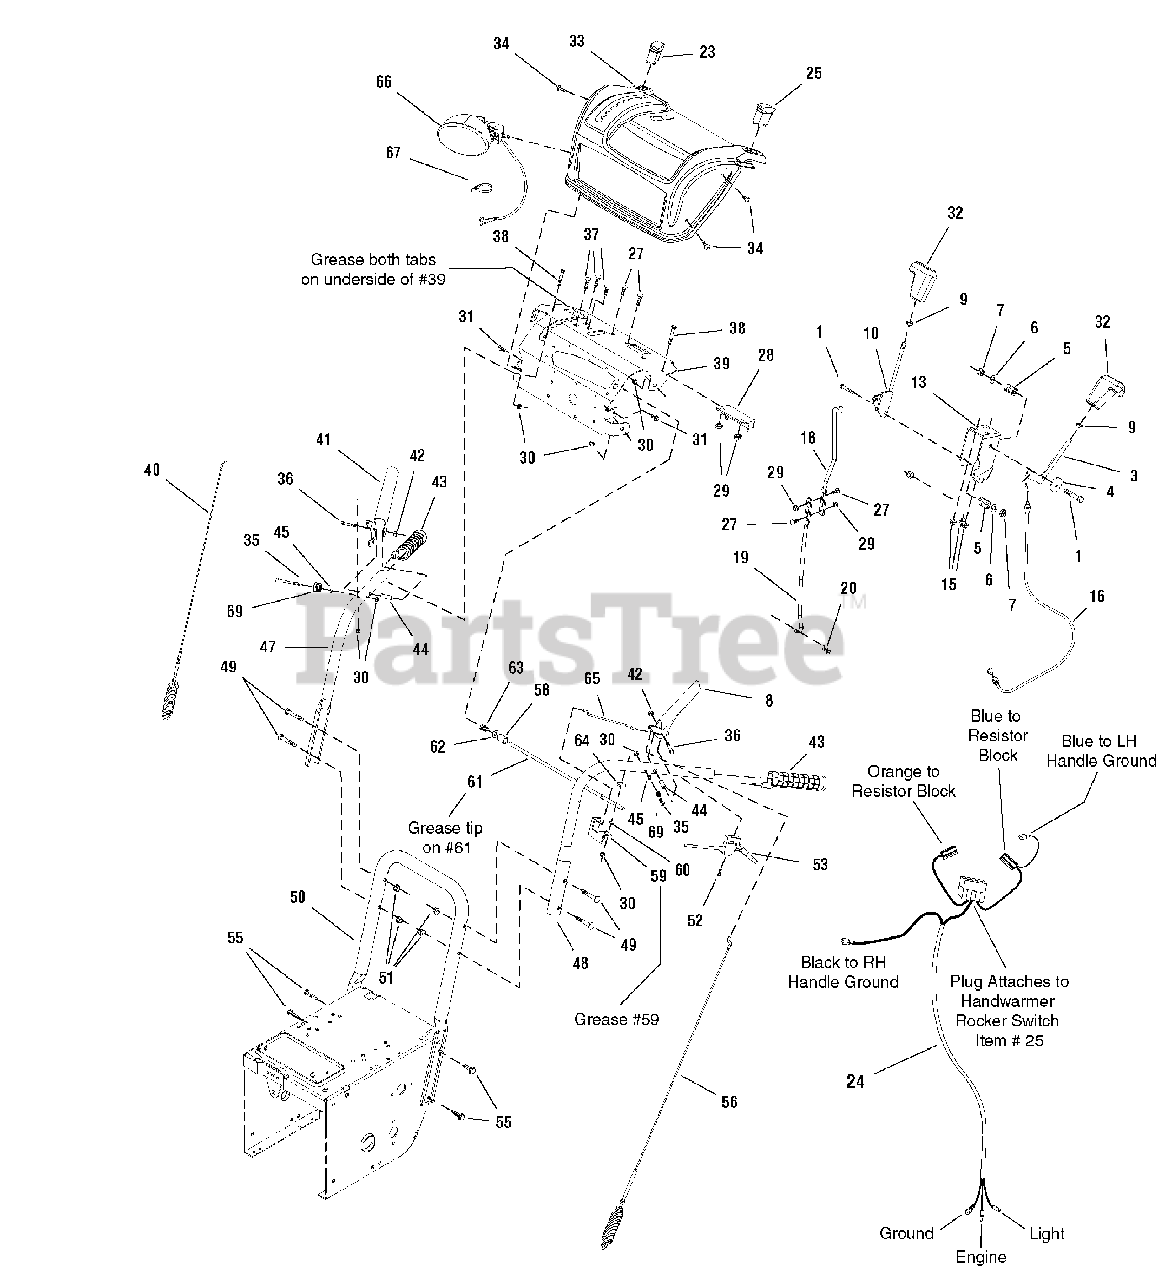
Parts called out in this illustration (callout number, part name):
1	CAPSCREW, Hex Head 3/8-16 x 2 G5
3	ROD, Chute
4	WASHER, 3/8 x 1.5
5	SPRING, .75, Compression
6	WASHER, 3/8
7	NUT, Hex Lock ESNA Light, 3/8-16
8	GRIP, Clutch L.H.
9	NUT, Hex Jam, 3/8-16
10	ROD & BRACKET ASSEMBLY, Speed
13	BRACKET, Control
15	NUT, Hex Flange Whiz Lock, 5/16-18
16	CABLE, Deflector Control
18	ROD, Shift, Upper
19	ROD, Shift, Lower
20	HAIRPIN, 1.19
23	SWITCH, Electronic Spout Rotate
24	HARNESS, Wiring Hand Warmers
25	SWITCH, Rocker Hand Warmer
27	CARRIAGE BOLT, 1/4-20 x 3/4 G5
28	RESISTOR BLOCK
29	NUT, Hex KEPS, 1/4-20 Conical Washer
30	NUT, Hex Lock ESNA Light 1/4-20
31	SCREW, Hex Washer Head Taptite, 1/4-20 x 5/8
32	GRIP, Lever
33	COVER, Panel
34	SCREW, Truss Head Torx Drive 1/4-20 x 3/4
35	CAPSCREW, Hex-Head, 1/4-20 x 2-1/2
36	CAPSCREW, Hex Head, 1/4-20 x 1-1/2 G5
37	CARRIAGE BOLT, 5/16-18 x 3/4 G5
38	CAPSCREW, Hex Head, 1/4-20 x 1-3/4 G5
39	SUPPORT, Dash Panel Cover
40	CABLE & SPRING ASSEMBLY, Auger Drive R.H.
41	GRIP, Clutch R.H.
42	NUT, Hex Centerlock 1/4-20
43	HAND GRIP, Heated
44	SPACER, Handle
45	SPACER, Handle Stop
47	HANDLE, Upper R.H.
48	HANDLE, Upper L.H.
49	CARRIAGE BOLT, 5/16-18 x 2-1/4 G5
50	HANDLE, Lower
51	NUT, Hex Flange ESNA, 5/16-18
52	SCREW, Pan Head Torx
53	ASSEMBLY, Trigger and Cable
55	CAPSCREW, Hex Head, 5/16-18 x 1, G5
56	CABLE, Front Drive
58	SPACER
59	BRACKET, Free Hand
60	SPACER, Powerdered Metal
61	ROD & SPRING ASSEMBLY, with Pin
62	WASHER, 1/2
63	SPRING, Compression
64	WASHER, 1/4
65	ROD, Hold Down
66	HEADLIGHT ASSEMBLY, Oval Clear
67	TIE, Self Locking
69	SPOOL CABLE, Auger Control
